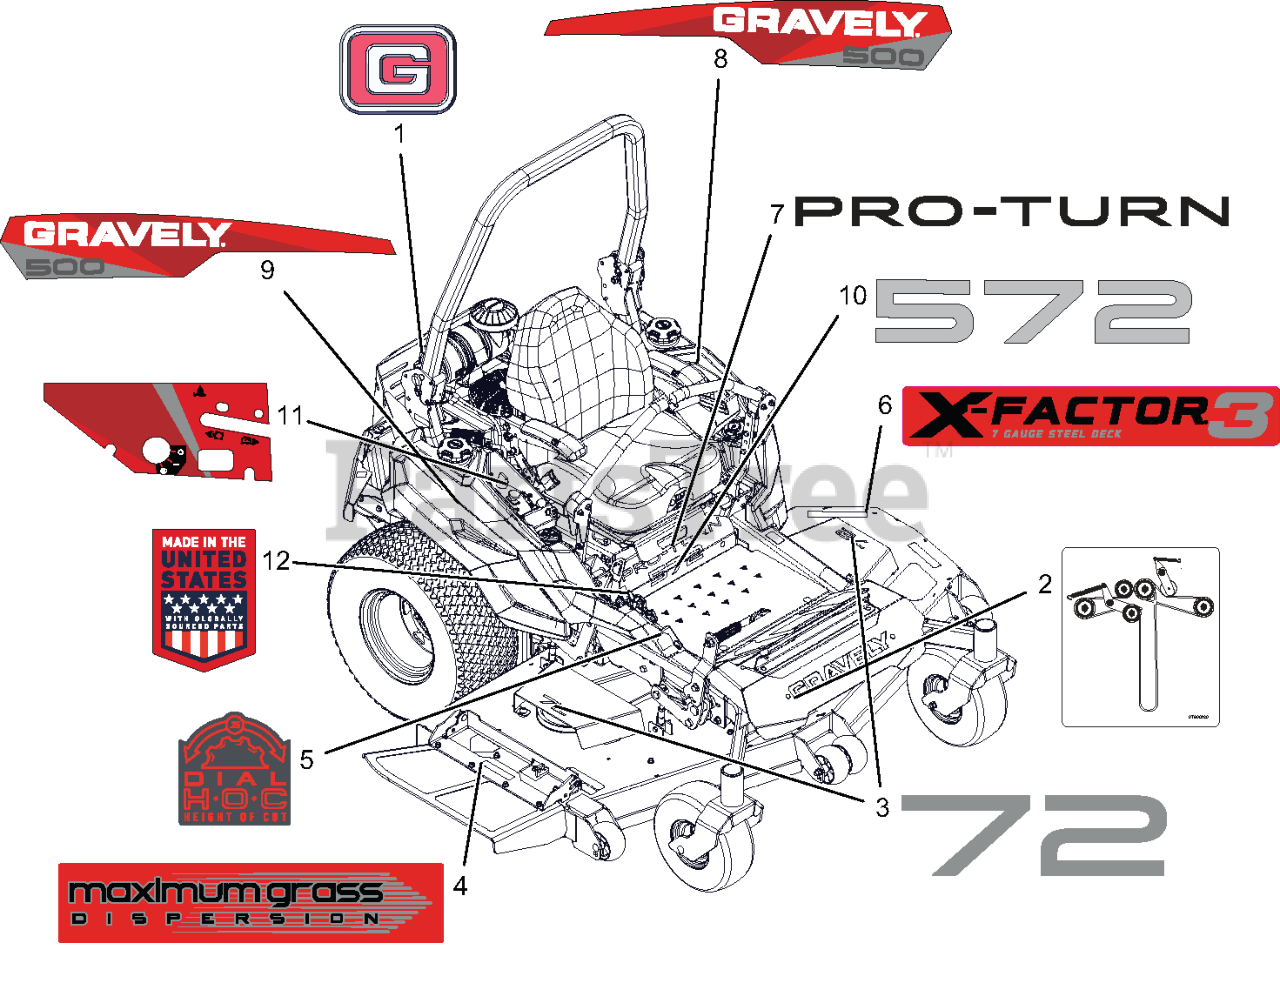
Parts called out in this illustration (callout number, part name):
1	DECAL, GRAVELY BRAND
2	DCL,BELT ROUTE-RH BK-SIDE IDLR
3	DECAL, DECK - 72
4	DECAL, DECK - MAX GRASS
5	DECAL, COVER - HOC
6	DECAL, DECK - X-FACTOR 3
7	DECAL, PRO TURN
8	DECAL- GRAVELY TANK - LH PT500
9	DECAL- GRAVELY TANK - RH PT500
10	DECAL 572
11	DECAL- CONTROL PANEL
12	DECAL- MADE IN USA
